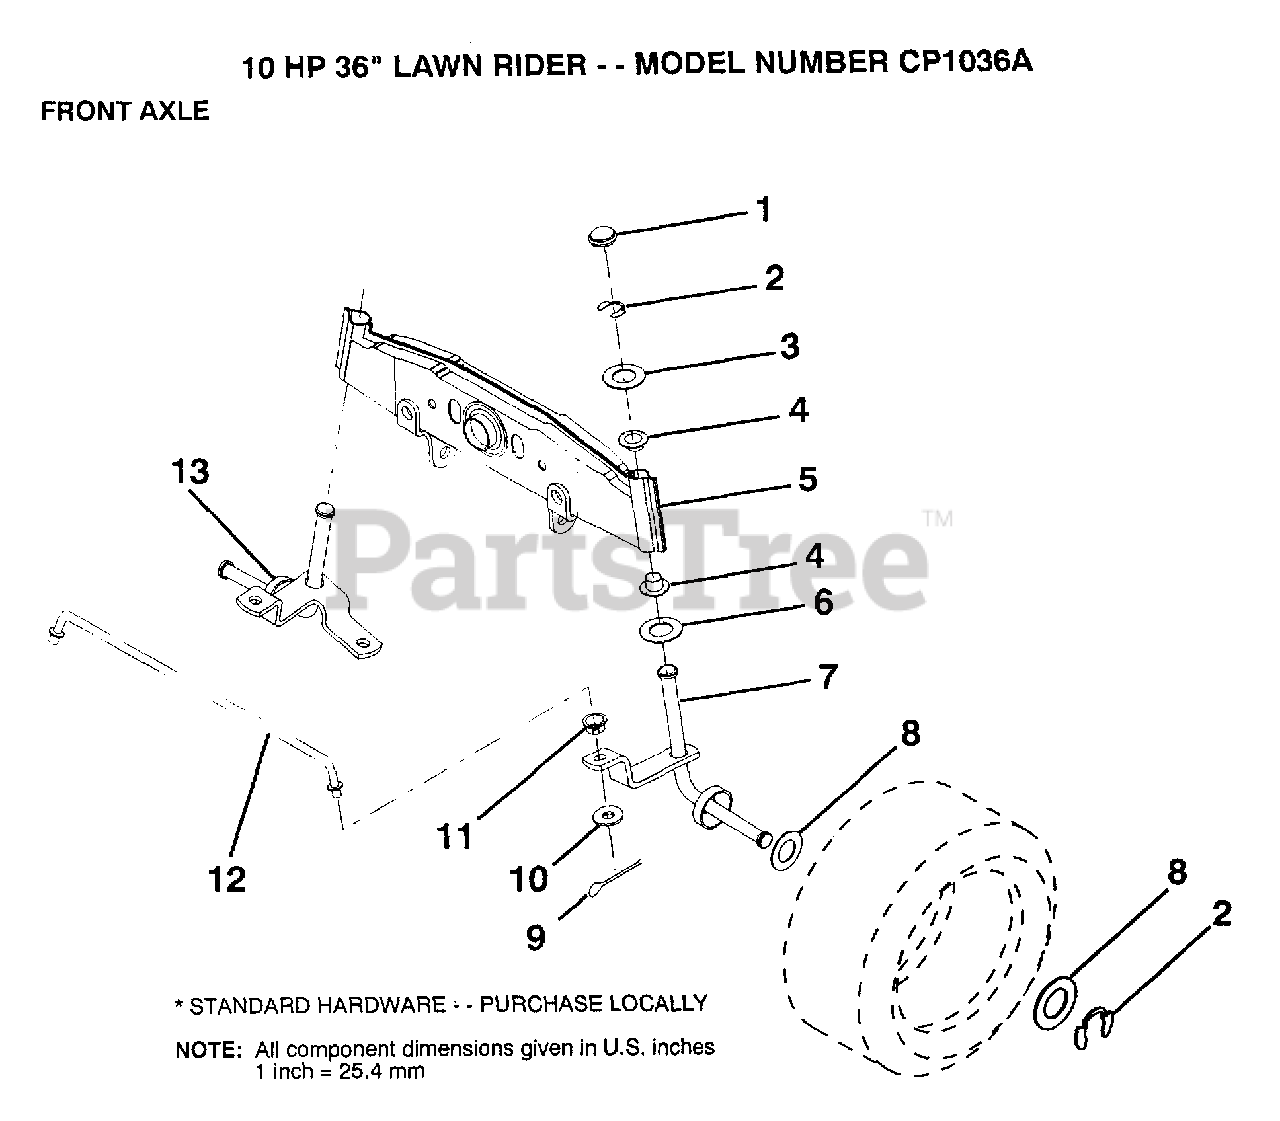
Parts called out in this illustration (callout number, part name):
1	CAP
2	RING
3	WASHER
4	NYLINER
5	AXLE FRONT
6	WASHER .T
7	SPINDLE RH
8	WASHER
9	COTTER PIN
10	WASHER
11	BUSHING.DRAGLINK
12	ROD TIE
13	SPINDLE LH
